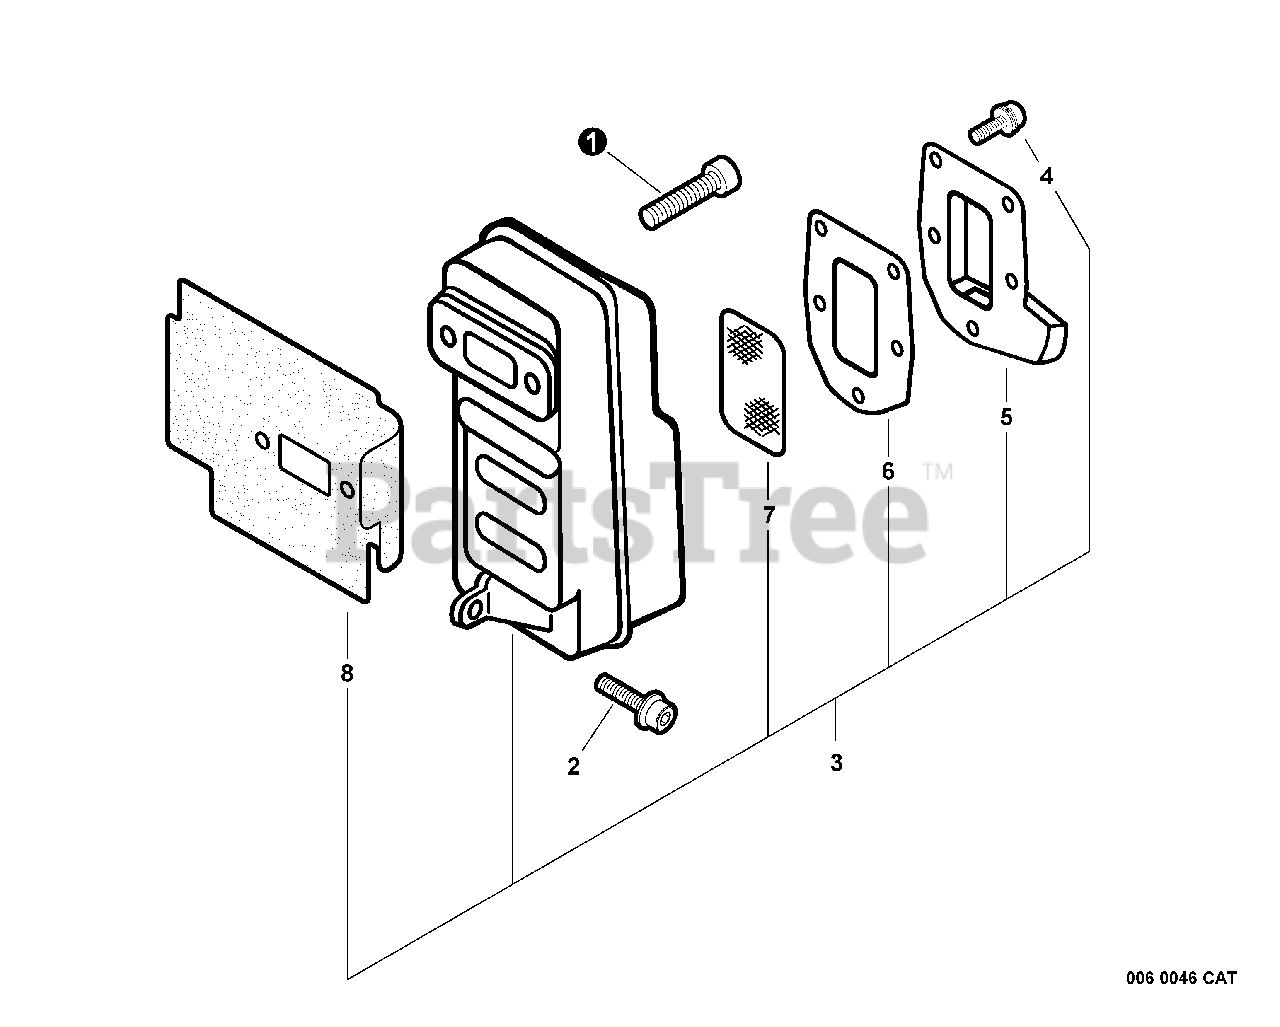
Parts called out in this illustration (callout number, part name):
1	BOLT 6×20
2	BOLT 5×16
3	MUFFLER ASSY
4	SCREW 4×10
5	GUIDE, EXHAUST
6	GASKET, EXHAUST
7	SCREEN, SPARK ARRESTER
8	HEAT SHIELD, EXHAUST
